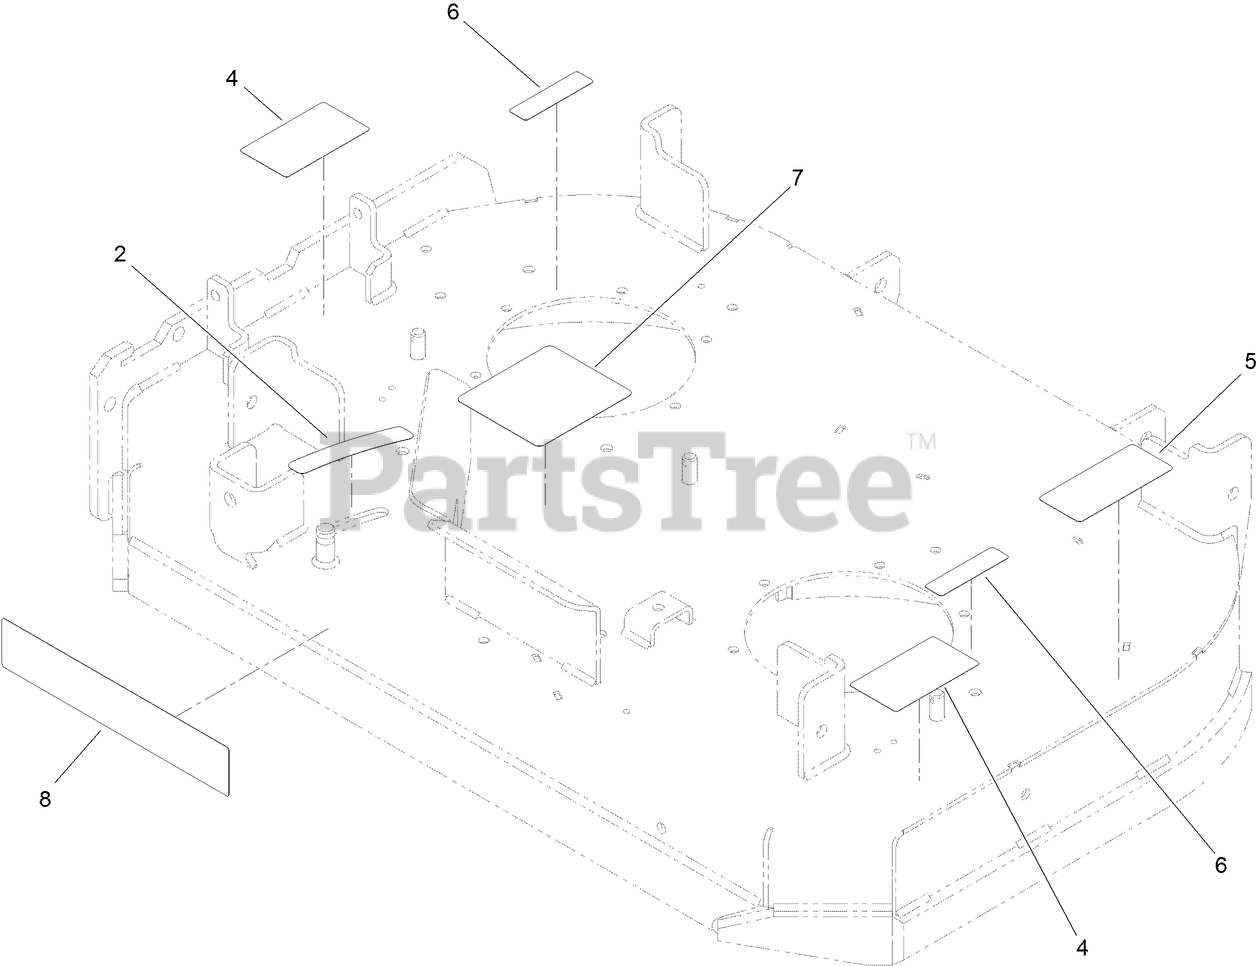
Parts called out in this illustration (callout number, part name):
2	DECAL-SETTING, BAFFLE
4	DECAL-DANGER
5	DECAL-TORQUE, BLADE BOLT
6	DECAL-DANGER
7	DECAL-ROUTING, BELT
